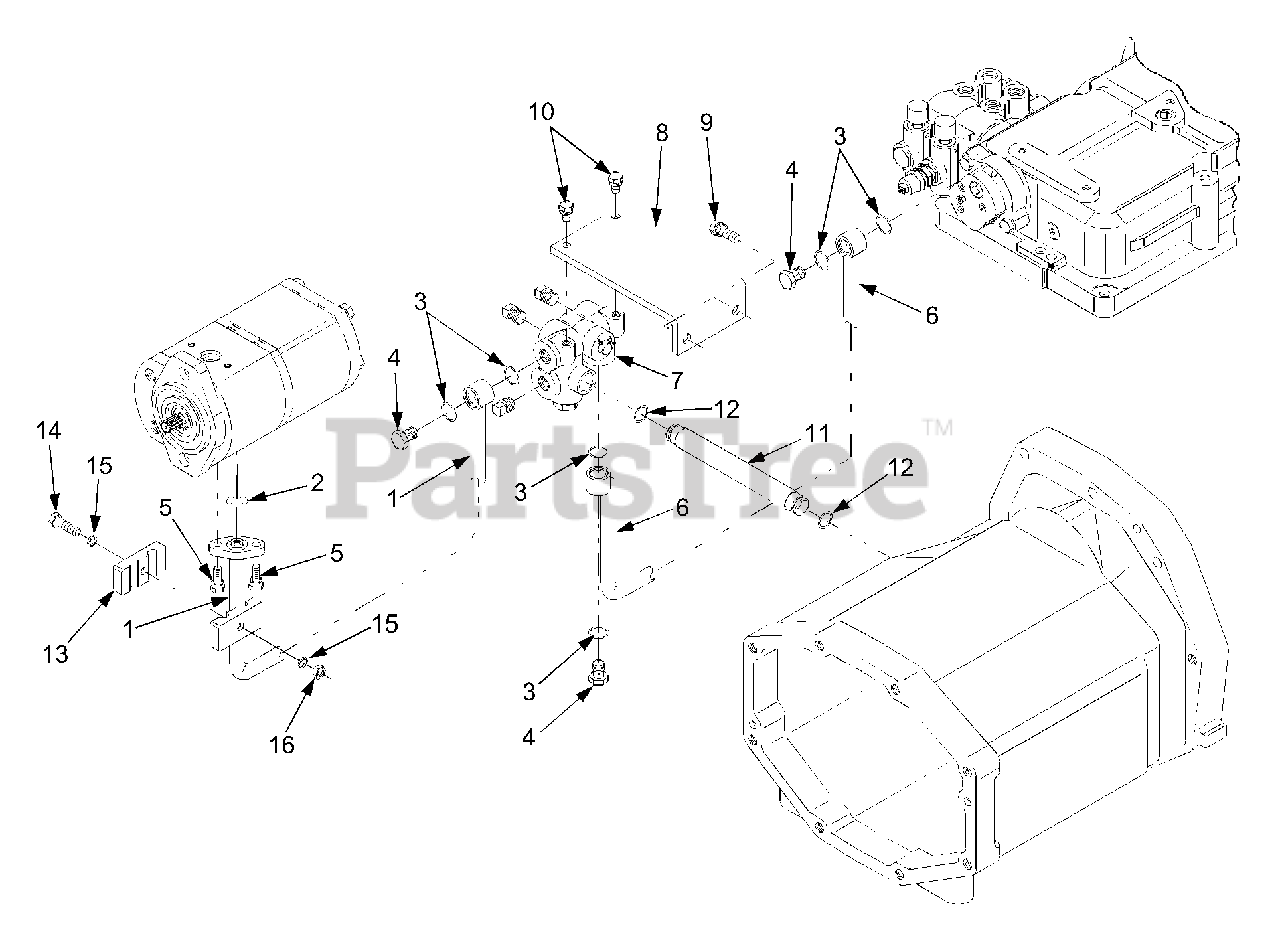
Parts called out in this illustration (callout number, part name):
1	Pipe 1, Hydraulic
6	Pipe 2, Hydraulic
7	Hydraulic Block Ass'y
8	Support, Hydraulic Block
13	Clamp 2, Pipe
15	Washer, Plain
